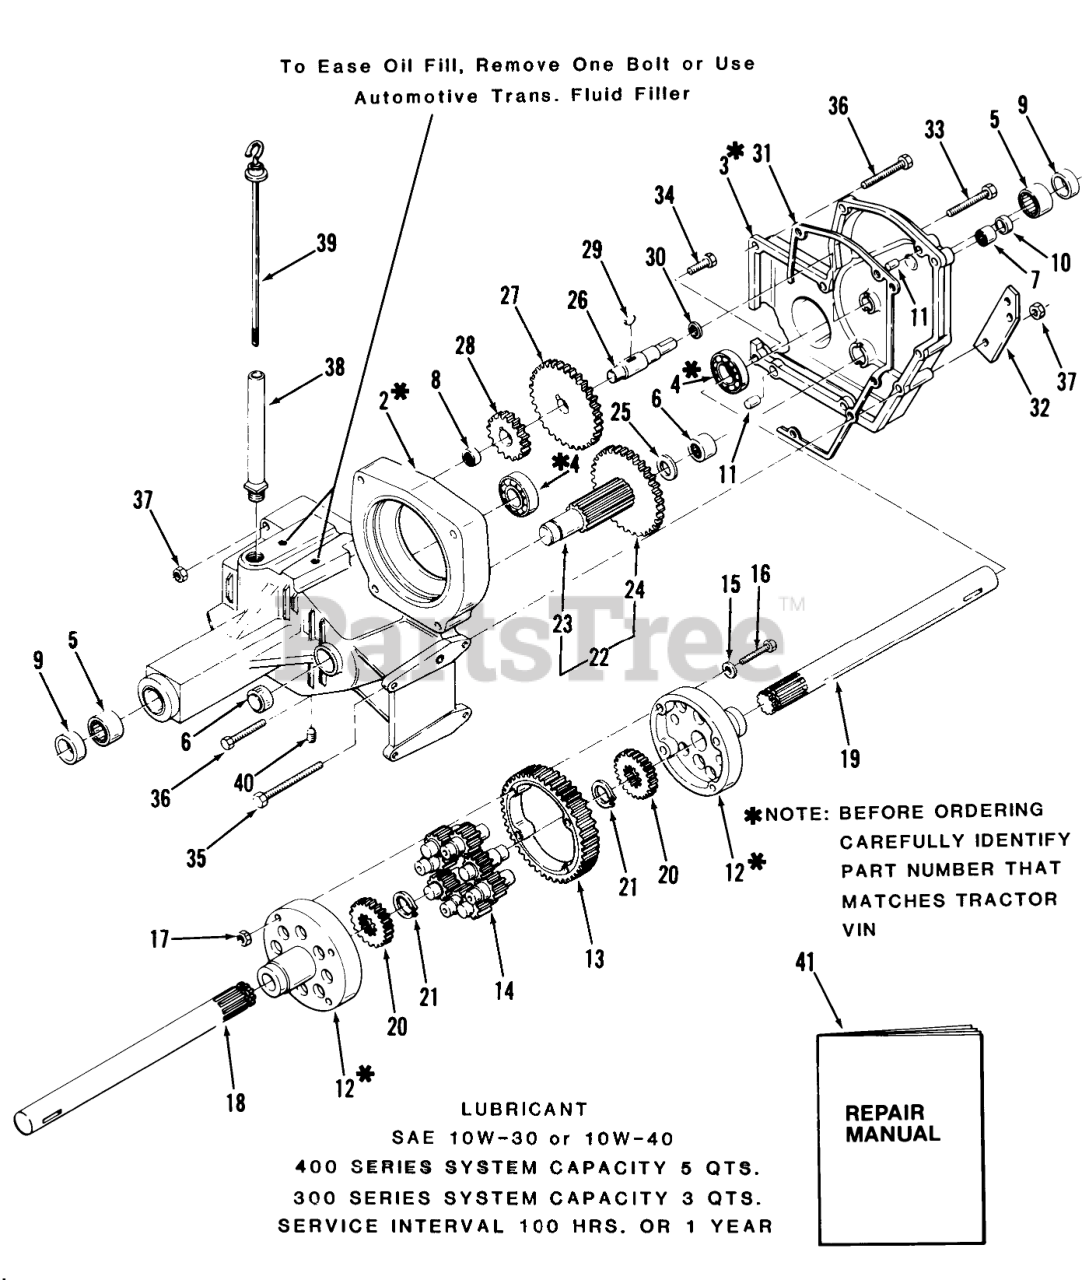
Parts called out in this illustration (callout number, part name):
2	TRANS CASE RH
3	Case-Transaxle LH
4	BALL BRG 1 1/2 I.D.
5	BEARING
6	BEARING-NEEDLE
7	NEEDLE BEARING
8	BEARING-NEEDLE
9	SEAL-OIL
10	Seal
11	PIN-LOCATING
12	DIFFERENTIAL END CAP
13	GEAR-DIFFERENTIAL RING, 43T
14	GEAR-PINION, 11T
15	WASHER
16	BOLT-HEX
18	AXLE-REAR RH
19	AXLE-REAR LH
20	GEAR-AXLE DIFFERENTIAL
21	RING-SNAP
22	ASSY GEAR
23	PINION SHAFT
24	GEAR 46T
25	WASHER-THRUST
26	SHAFT GEAR
27	GEAR 46 TEETH
28	GEAR 20 TEETH
29	Key
30	Race Thrust
31	GASKET-TRANSMISSION
32	BRACKET-BRAKEB
33	Bolt
34	Bolt
35	H H C S
36	Screw-Hex. Hd.
37	Nut
38	NIPPLE-TRANS FILL
39	ASSY-DIPSTICK
40	PLUG 1/4 PIPE ALLEN
41	Repair Manual
